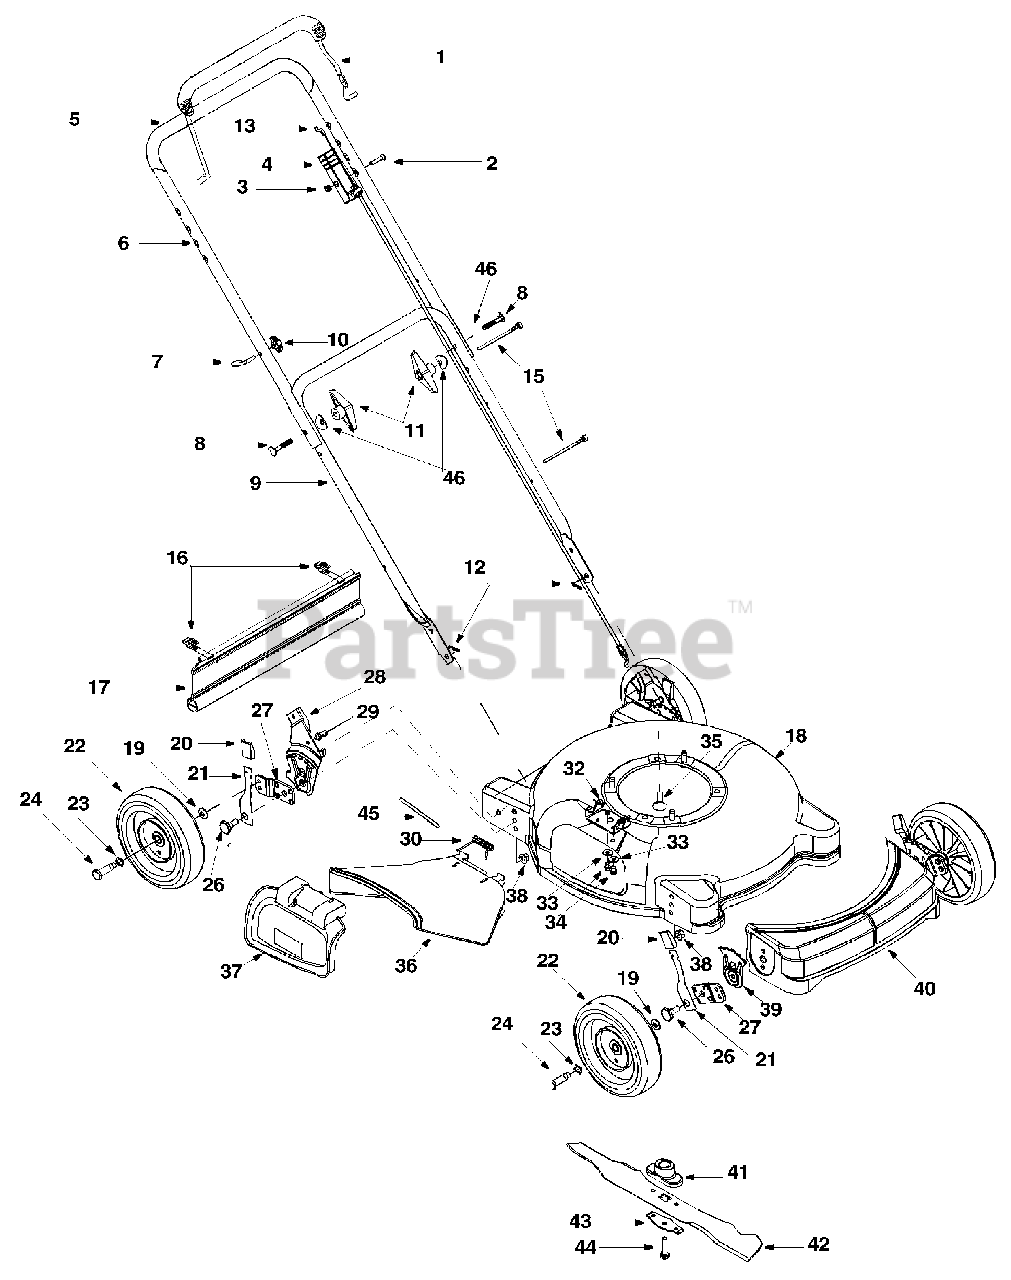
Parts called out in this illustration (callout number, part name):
1	Control Handle Assembly
2	Oval C-Sunk Screw
3	Hex Lock Nut
4	Control Housing
5	Foam Grip
8	Carriage Bolt
11	Hand Knob
12	Hairpin Clip
13	Control Cable 40.5"
15	Cable Tie
16	Hinge Clip
17	Trail Shield
20	Knob: Height Adjustment
21	Lever: Spring
22	Wheel Assembly
23	Wave Washer
24	Axle Bolt
26	Shoulder Bolt
29	Stake Bolt
30	Torsion Spring
31	Height Adjust. Assembly RH
33	Bell Washer
34	Self-tapping Screw
35	Self-tapping Sems Screw
36	Chute Deflector
37	Mulching Plug Assembly
38	Hex Lock Nut
39	Height Adjustment Plate
40	Cover: Front End
41	Blade Adapter
42	20" Mulching Blade
43	Blade Bell Support
45	Hinge Pin
46	Saddle Washer
